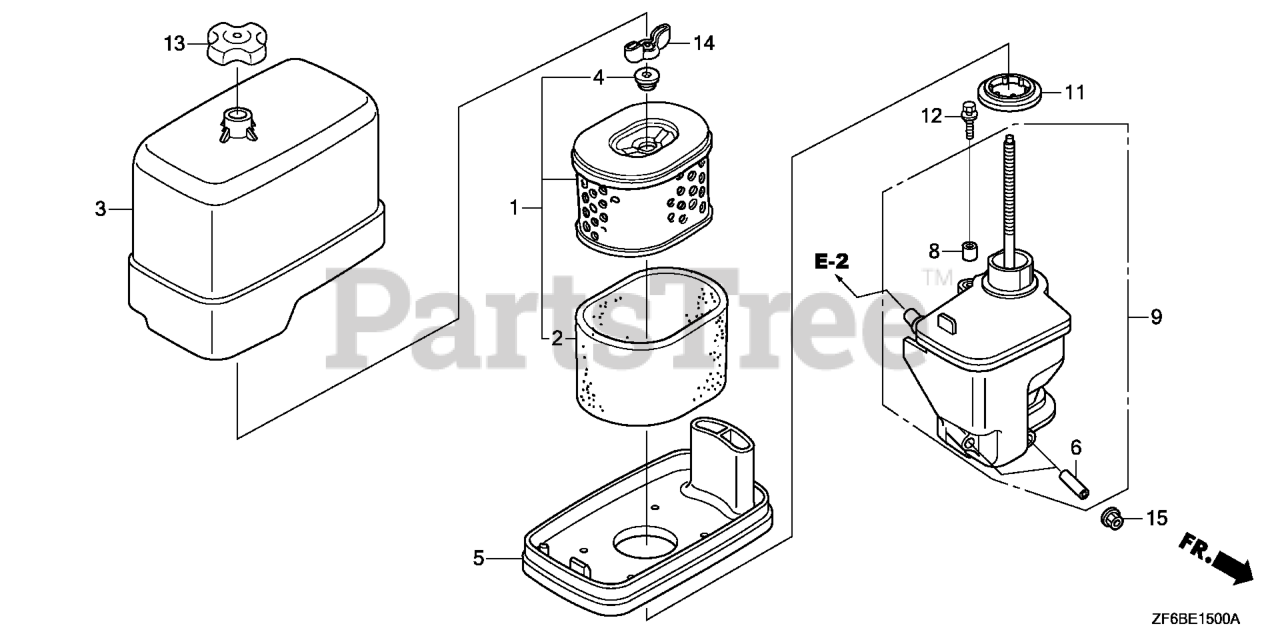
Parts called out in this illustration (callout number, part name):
1	ELEMENT, AIR CLEANER
2	FILTER (OUTER)
3	COVER, AIR CLEANER HOUSING
4	GROMMET, AIR CLEANER
5	NOSE, MUFFLER
6	COLLAR, AIR CLEANER
8	COLLAR B, AIR CLEANER
9	ELBOW, AIR CLEANER
11	GASKET, AIR CLEANER HOUSING
12	BOLT-WASHER (6X22)
13	NUT, AIR CLEANER COVER
14	WINGNUT, TOOL BOX SETTING
15	NUT, FLANGE (6MM)
